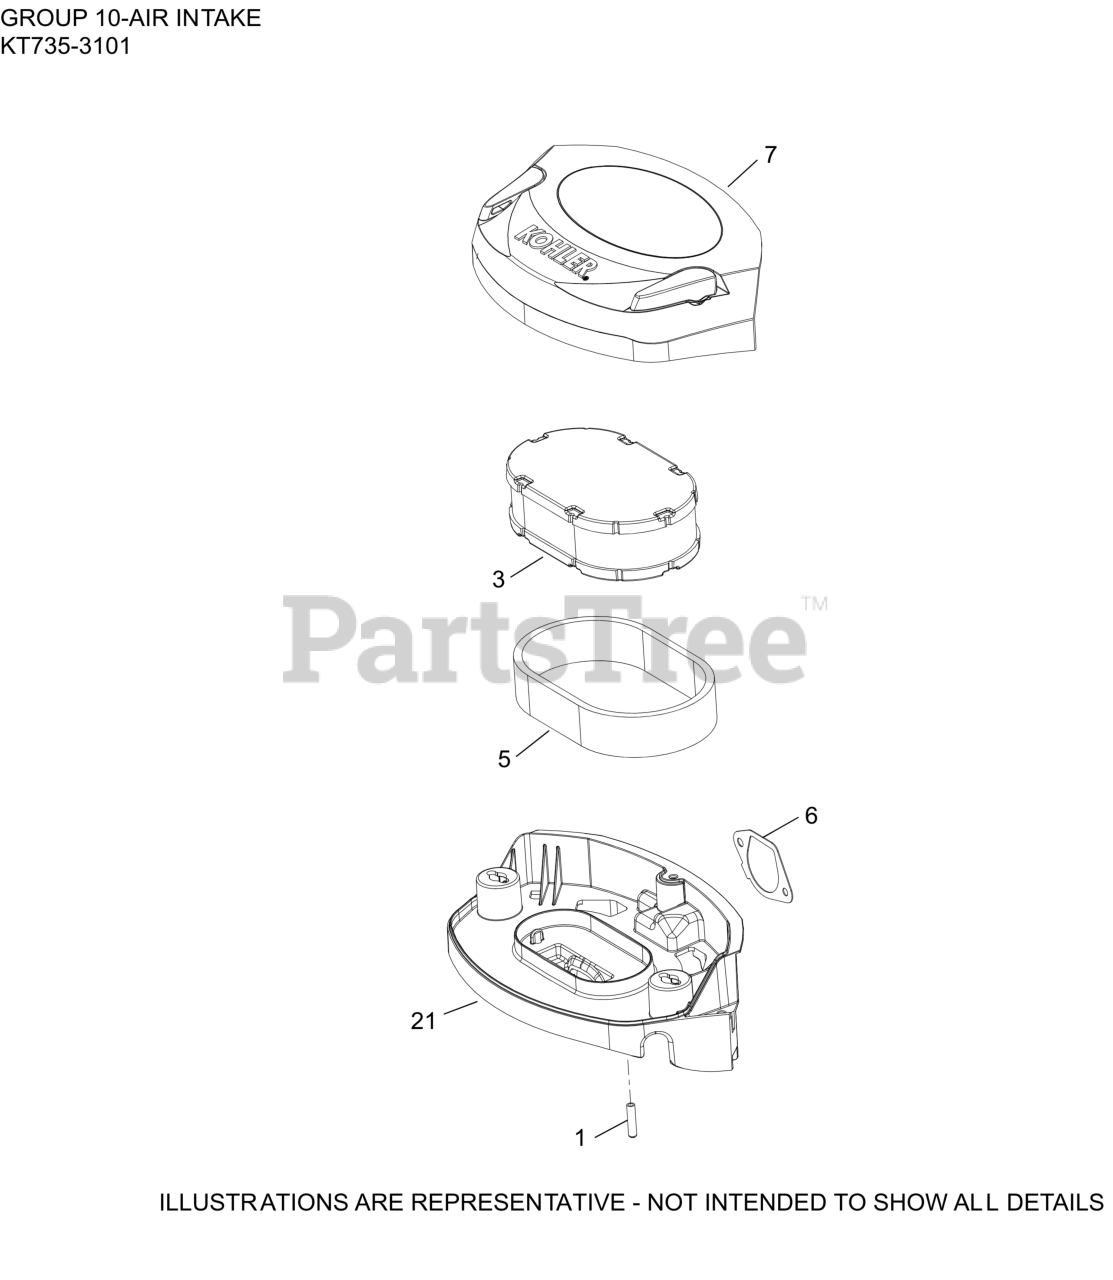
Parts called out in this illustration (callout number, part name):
1	CAP, MASKING
3	ELEMENT, AIR FILTER
5	ELEMENT, PRE-CLEANER
6	GASKET, AIR CLEANER BASE
7	COVER ASSEMBLY, AIR CLEANER
21	BASE ASSEMBLY, AIR CLEANER
